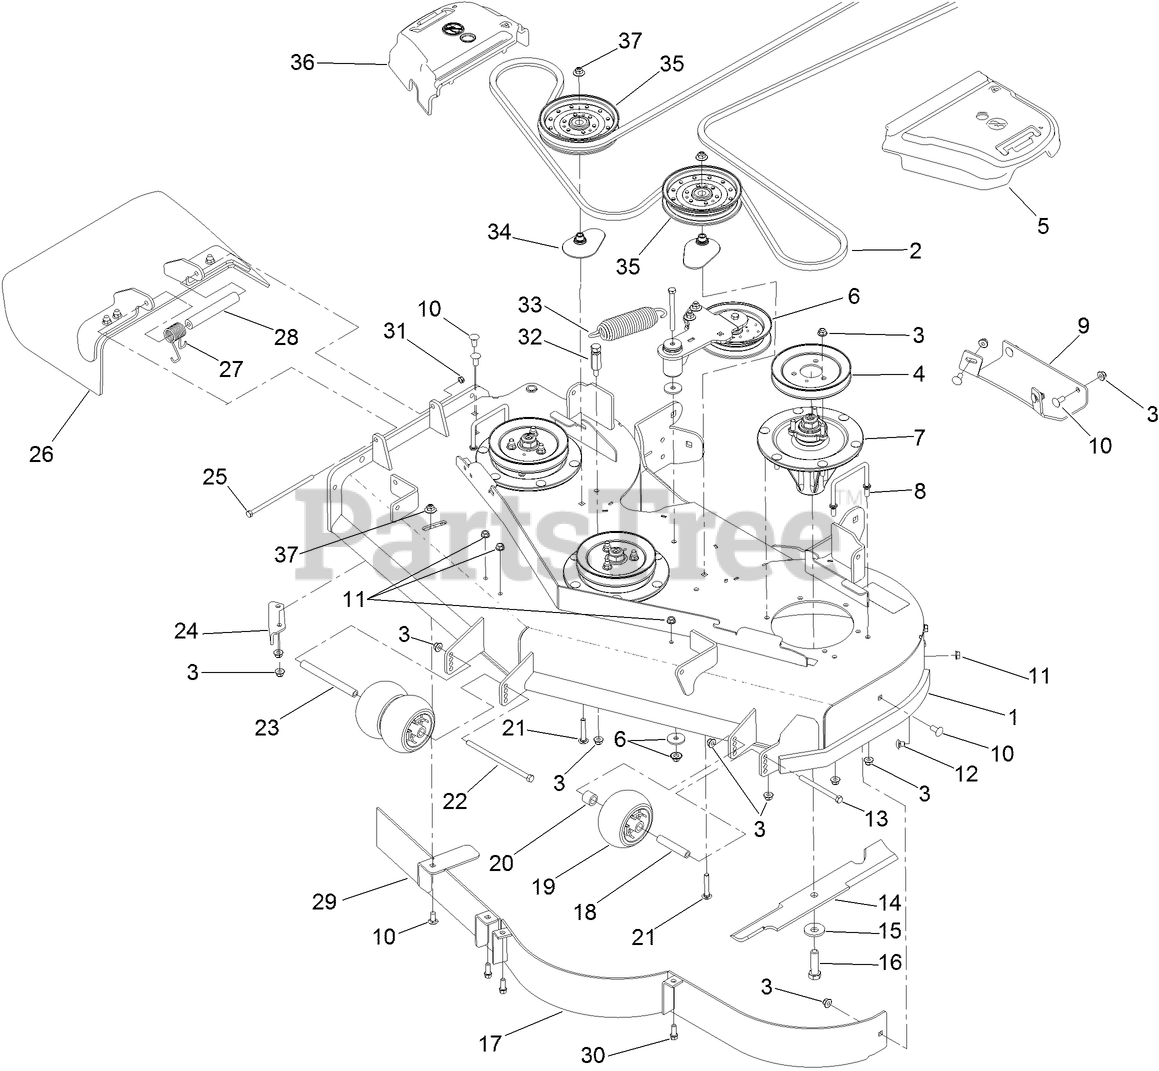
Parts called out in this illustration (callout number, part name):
1	DECK DECAL ASM
2	BELT-V
3	NUT-HF, NI
4	PULLEY
5	COVER-BELT, LH
6	IDLER ARM ASM
7	SPINDLE ASM
8	WIREFORM-COVER
9	PLATE-SKID
10	SCREW-CARR
11	NUT-HHF, WHIZ
12	SCREW-CARR
13	SCREW-HH
14	BLADE-18IN, HI FLOW
15	Washer-Blade Bolt, Heavy
16	SCREW-BLADE
17	BAFFLE ASM
18	TUBE-SPANNER
19	ROLLER-SCALP, ANTI
20	TUBE-SPACER
21	BOLT-CARR, SHORT NECK
22	SCREW-HH
23	SPACER-WHEEL
24	BAFFLE-DISCHARGE
25	SCREW-HH
26	RUBBER DEFLECTOR ASM
27	SPRING-TORSION
28	SPACER
29	BAFFLE ASM
30	SCREW-HWH
31	NUT-LOCK, NI
32	ANCHOR-SPRING, TALL
33	SPRING-EXTENSION
34	SPACER-PULLEY
35	PULLEY-IDLER, FLAT
36	COVER-BELT, RH
37	NUT-FLANGE, NI
